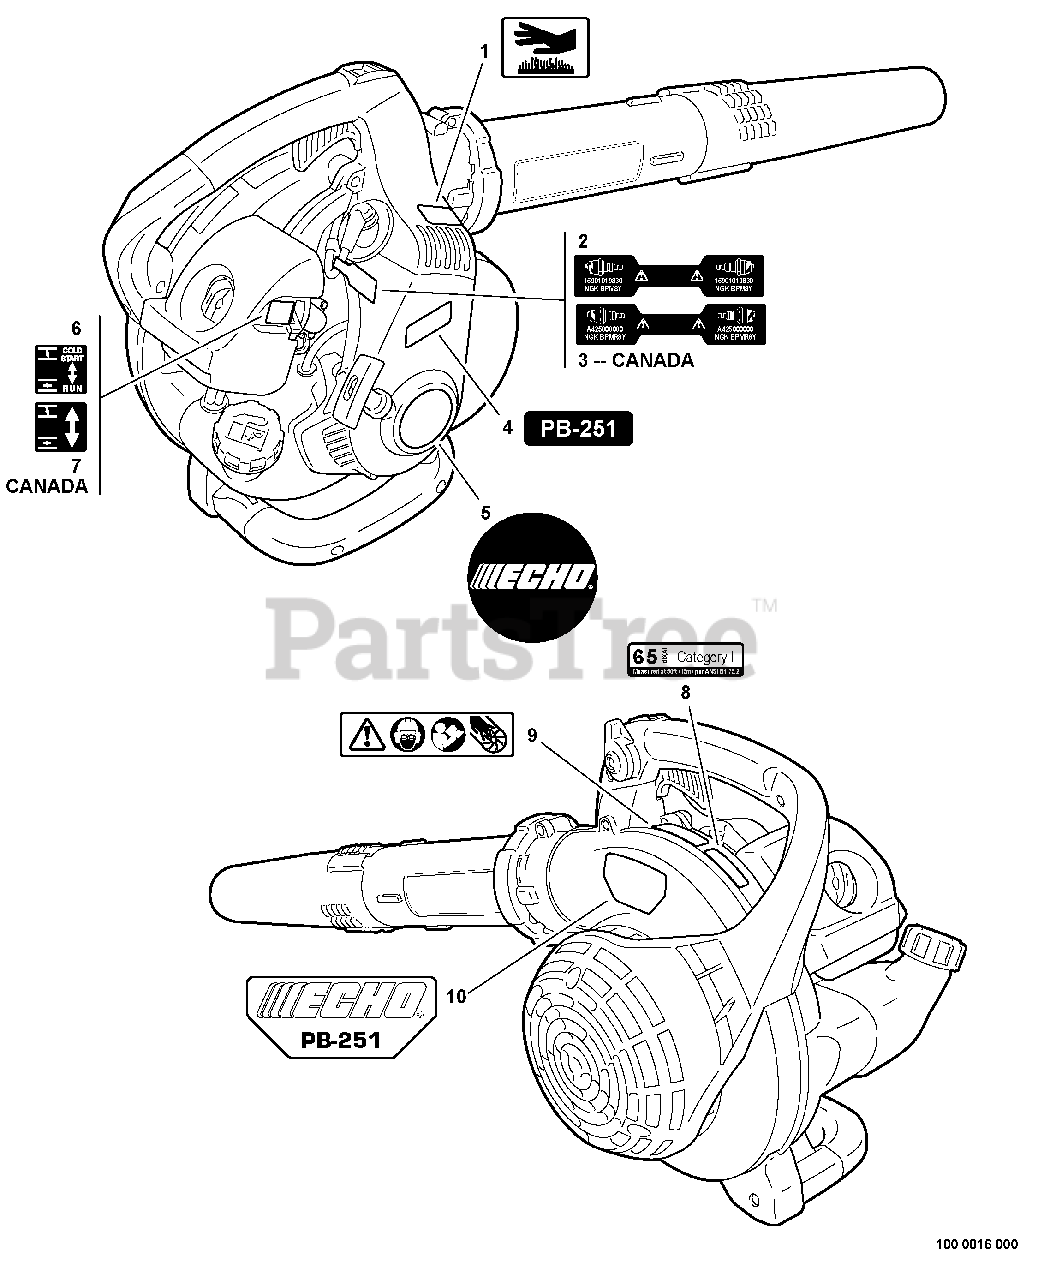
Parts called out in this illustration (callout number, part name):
1	LABEL - HOT SURFACE
2	LABEL - SPARK PLUG -- BPM-8Y
3	LABEL - SPARK PLUG -- BPMR-8Y
4	LABEL - MODEL PB-251
5	LABEL - ECHO
6	LABEL - CHOKE
7	LABEL - CHOKE
8	LABEL - NOISE 65dB(A) CAT I
9	LABEL - CAUTION
10	LABEL - MODEL PB-251
